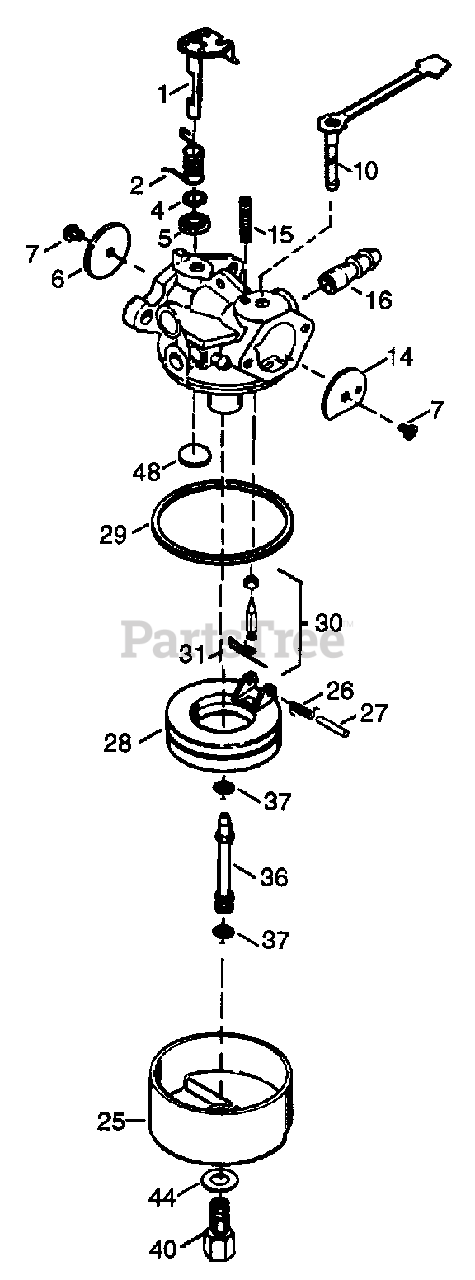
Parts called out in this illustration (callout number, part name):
1	Throttle Shaft & Lever Asm.
2	Throttle Return Spring
4	Dust Seat Washer
5	Dust Seat (Throttle)
6	Throttle Shutter
7	Shutter Screw
10	Choke Shaft & Lever Asm.
14	Choke Shutter
15	Choke Positioning Spring
16	Fuel Fitting
25	Float Bowl
26	Float Dampening Spring
27	Float shaft
29	Float Bowl "O" Ring
30	Inlet Needle, Seat & Clip (Incl. Ref. #31)
31	Spring Clip
36	Main Nozzle Tube
37	"O" Ring, Main Nozzle Tube
40	High Speed Bowl Nut
44	Bowl Nut Washer
48	Welch Plug
